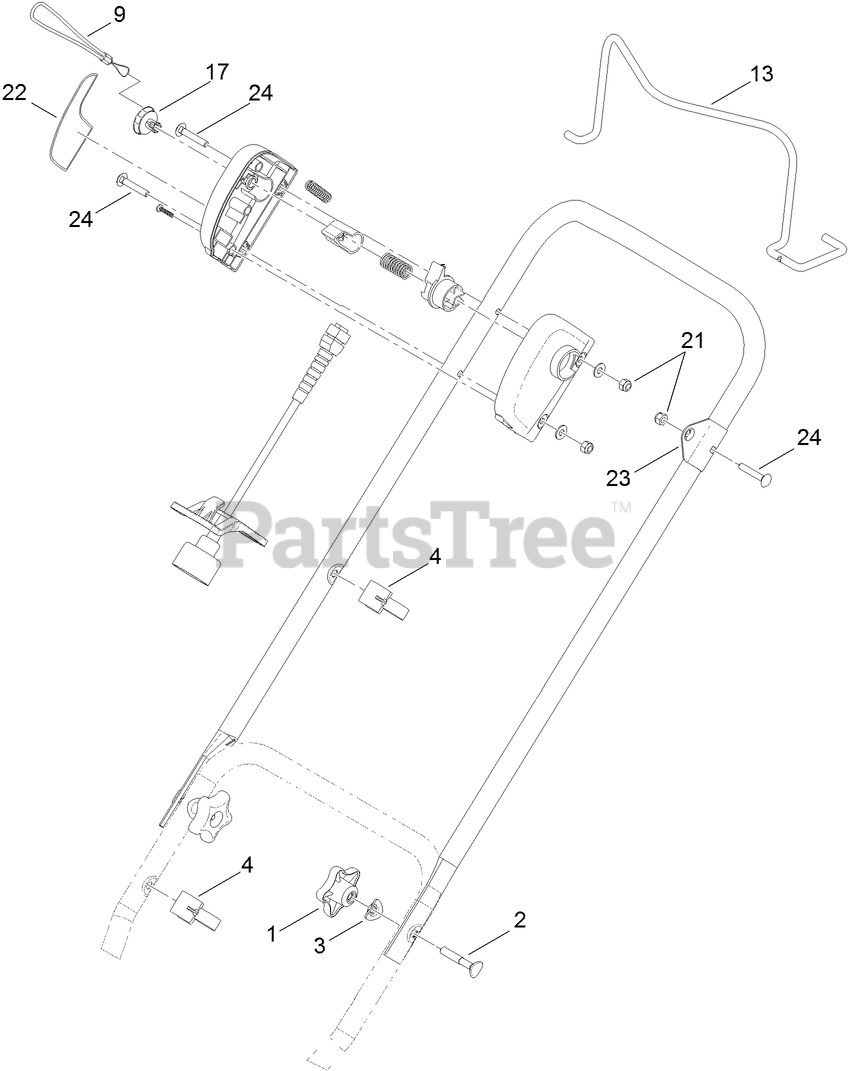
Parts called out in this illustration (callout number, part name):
1	KNOB-HANDLE
4	GUIDE-CABLE
21	NUT-LOCK, NI
22	DECAL-OPERATION
23	BRACKET-BAIL
24	SCREW-CARR
